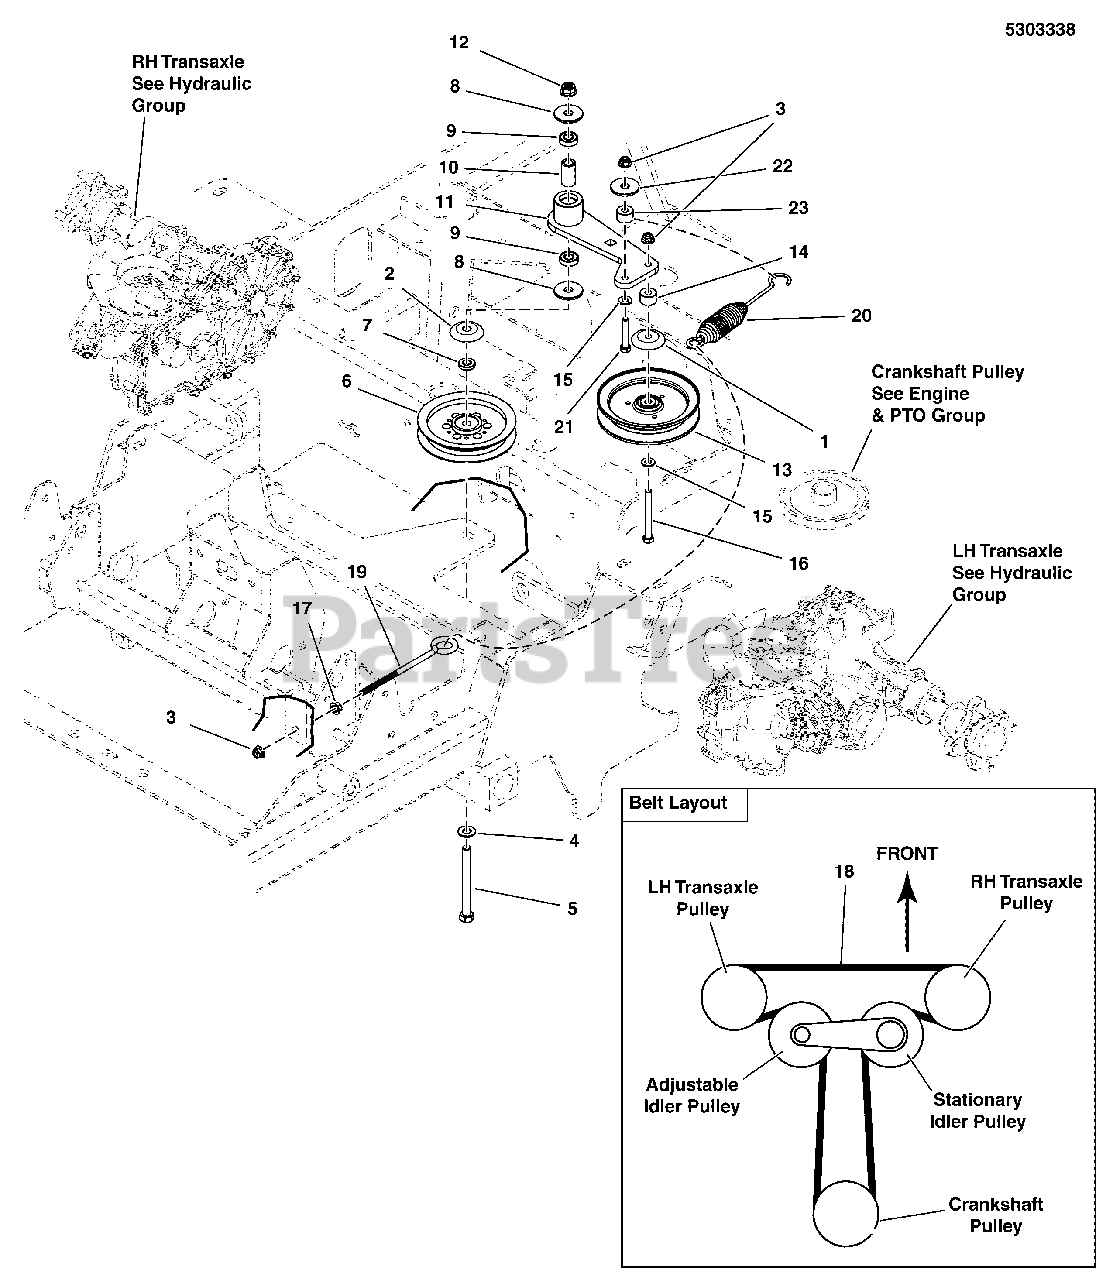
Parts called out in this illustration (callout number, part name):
1	SHIELD, BEARING PULLEY, 3/8ID, CZ
2	SHIELD, PULLEY BEARING, CZ
3	NUT, Hex Flange, Nylock, 3/8-16
4	WASHER, 1/2
5	BOLT, 1/2-13 X 5" GD5 YZ
6	PULLEY, IDLER 5"OD .500ID, .75W STL
7	SPACER, .52 X 1.00 X .22, PM, CZ
8	SPACER, Idler Arm
9	BEARING, Ball
11	WELD, IDLER ARM, PUMP DRIVE - BLK
12	NUT, Hex Flange, 1/2-13
13	PULLEY, C-SEC, V-IDLER, 6.25"ODX3/8ID
15	WASHER, 3/8" GR. 9 FLAT
16	BOLT, 3/8-16 X 2-1/2"
17	GUARD HOLD DOWN, Complete (includes Ref 11-14)
18	BELT, SPA-SEC, 92" EL, ARAMID, WRAPED
19	EYEBOLT, 3/8-16 X 8, 3 THRD, 1 EYE, CZ
20	SPRING-EXT, 1.25OD X 9.3LG X .142WR, BLK
21	CAPSCREW, Hex Head, 3/8-16 X 1-3/4
22	WASHER, Fender, 3/8
23	SPACER, SHOULDER
